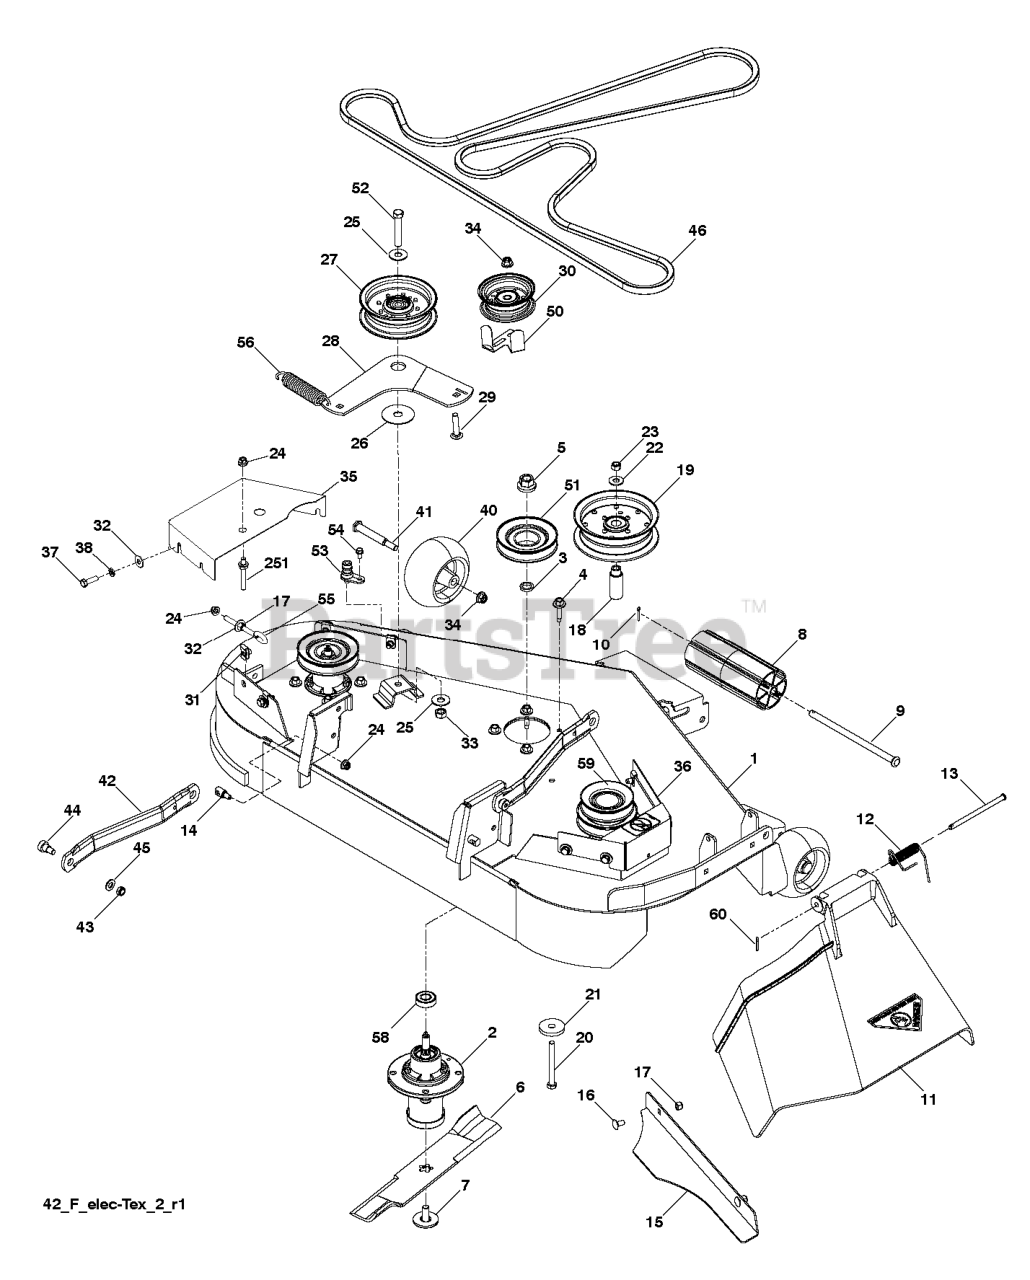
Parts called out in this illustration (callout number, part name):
1	DECK 42" ORANGE
2	MANDREL.DECK.ASSEMBLY
3	WASHER.SPACER.MANDREL
4	WASHER HEAD SCREW
5	NUT.FLANGE.LOCK.TOP
6	BLADE, 14 5/8"
7	BOLT.WASHER.ASM.7/16-2
8	NOSE ROLLER 48"
9	ROD.ROLLER.NOSE.NARROW.48"
10	PIN.COTTER.5/16.BOW TI
11	DISCHARGE CHUTE 42"
12	SPRING - TORSION
13	PIN-CLEVIS 5/16 DIA X 5.19 ZD
14	STUD.FASTNER.W/ANTI-ROTATE
15	PLATE.CONFINEMENT.42"
16	CARRIAGE BOLT 5/16C X 5/8"
17	NUT 5/16 NYLOC
18	BUSHING, IDLER
19	PULLEY, IDLER
20	HCS 3/8-16 X 3-1/2 GR5 ZD
21	SPINDLE WASHER
22	WASHER 3/8 FLAT
23	NUT 3/8-16 NYLOC
24	5/16-18 NYLOC FLANGE NUT
25	WASHER 7/16 FLAT ZD
27	PULLEY.IDLER.MWR.STATI.LH
28	ARM IDLER RAW
29	RHSNB 3/8-16X1-3/4
30	PULLEY.IDLER.FLAT
31	U-CLIP 5/16-18 NUT RETAINER
32	WASHER 5/16 FLAT
33	NUT 7/16-14 HEX WHIZ LK
34	NUT 3/8-16 HEX FLG NYLOC ZD
35	SHIELD.BELT.LH.ORANGE
36	SHIELD, BELT, RH 42 ORG
37	HCS 5/16C X 1
38	WASHER.LOCK.HVY.HLCL.SPR.5/16
40	GAUGE WHEEL
41	BOLT.SHOULDER.3/8-16X3-5/8.
42	ARM.SUSPENSION.MOWER
43	NUT HEX 3/8-16 NYLON, THIN
44	SB 3/8-16 X 3/8 SKT HD ZD
45	WASHER 3/8 SAE FLAT
46	BELT, 42" FAB DECK
50	BELT GAURD
51	PULLEY, MANDREL 4.08 OP
52	BOLT 7/16-14 X 2-1/2 GR 5 ZD
53	PORT.WASHOUT
54	BOLT 1/4-20 X 1/2 HWST
55	EYE BOLT 5/16 X 3.50
58	BEARING, BALL
59	PULLEY, COLLECTION 42
60	RETAINER CLIP
251	KEEPER.BELT.ENGINE
